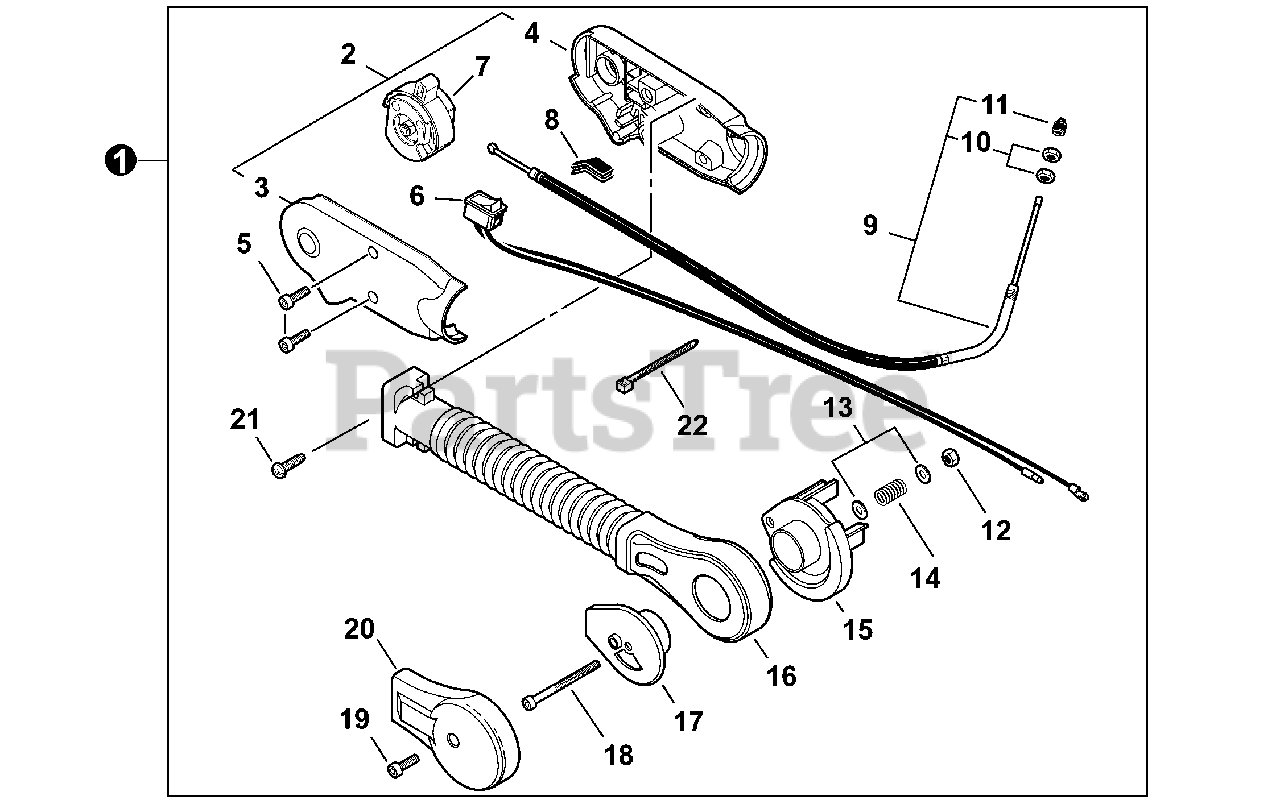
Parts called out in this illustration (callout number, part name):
1	THROTTLE CONTROL KIT - HIP MOUNT
2	GRIP SET, THROTTLE
3	GRIP, LEFT THROTTLE
4	GRIP, RIGHT THROTTLE
5	BOLT 5×14
6	SWITCH, ON-OFF
7	CONTROL, THROTTLE
8	GROMMET
9	CABLE ASSY, THROTTLE
10	NUT 6 MM
11	CAP, DUST
12	NUT, LOCK M5
13	WASHER 5.5×18×1
14	SPRING, COMPRESSION Ø9.53×24.13
15	BRACKET, ARM - INNER
16	ARM, THROTTLE CONTROL
17	BRACKET, ARM - OUTER
18	SCREW M5×80
19	BOLT 5×14
20	BRACKET, ARM - OUTER
22	STRAP, TIE
